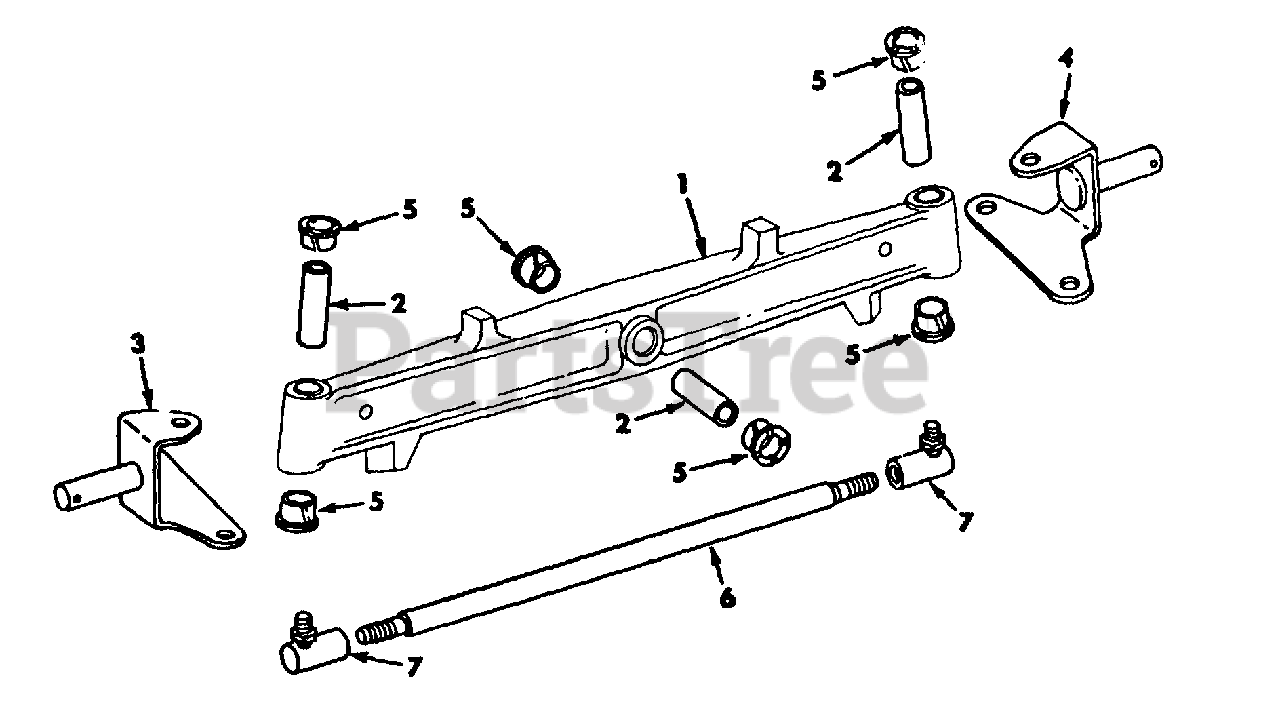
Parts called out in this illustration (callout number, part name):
1	AXLE ASSY, FRONT
2	BUSHING, FRONT AXLE
3	ARM ASSY, SPINDLE RH
4	ARM ASSY. SPINDLE LH
5	BEARING, FRONT AXLE
7	JOINT, TIE ROD
